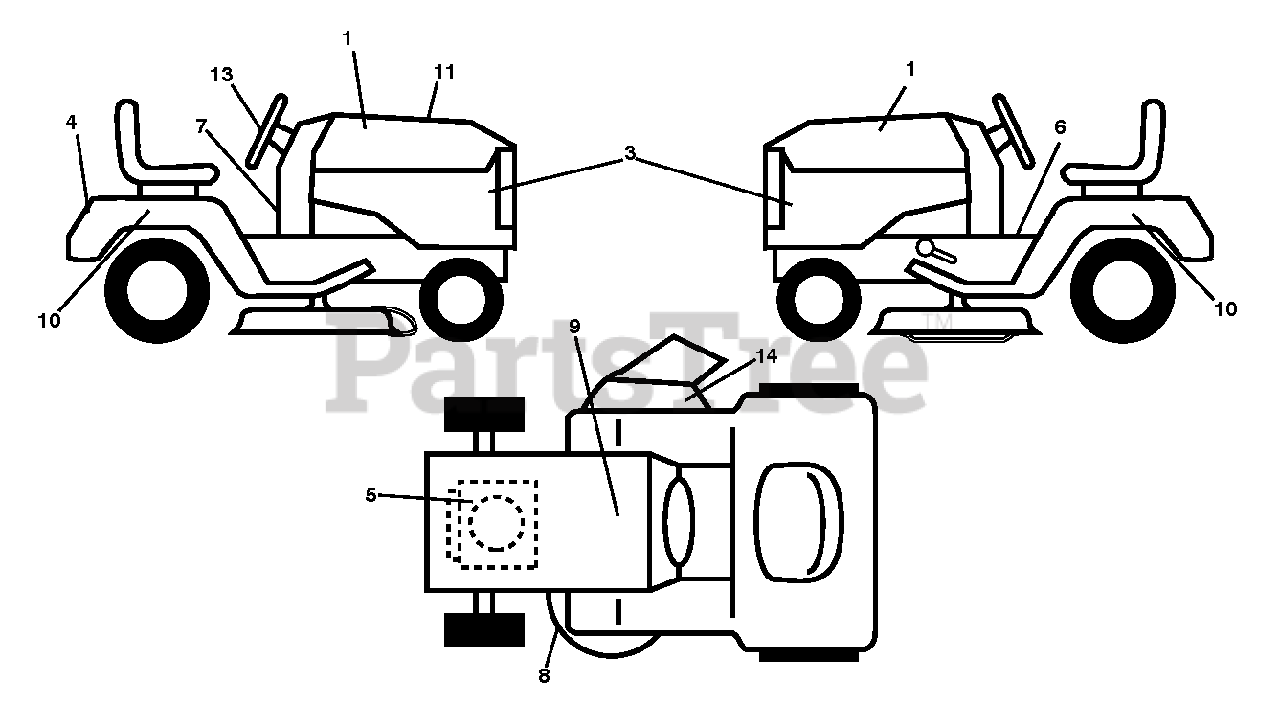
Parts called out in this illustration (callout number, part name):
5	DECAL.ENG.BS.23HP.XRD.TWIN
6	Fender Engine Warning Decal
8	DECAL.WARN.KEEP.HAND.AWAY
9	DECAL BTRY SYMBOLS
13	DECAL.STEER.WHEEL.POULAN.PRO
14	DECAL V BELT SCHEMATIC
